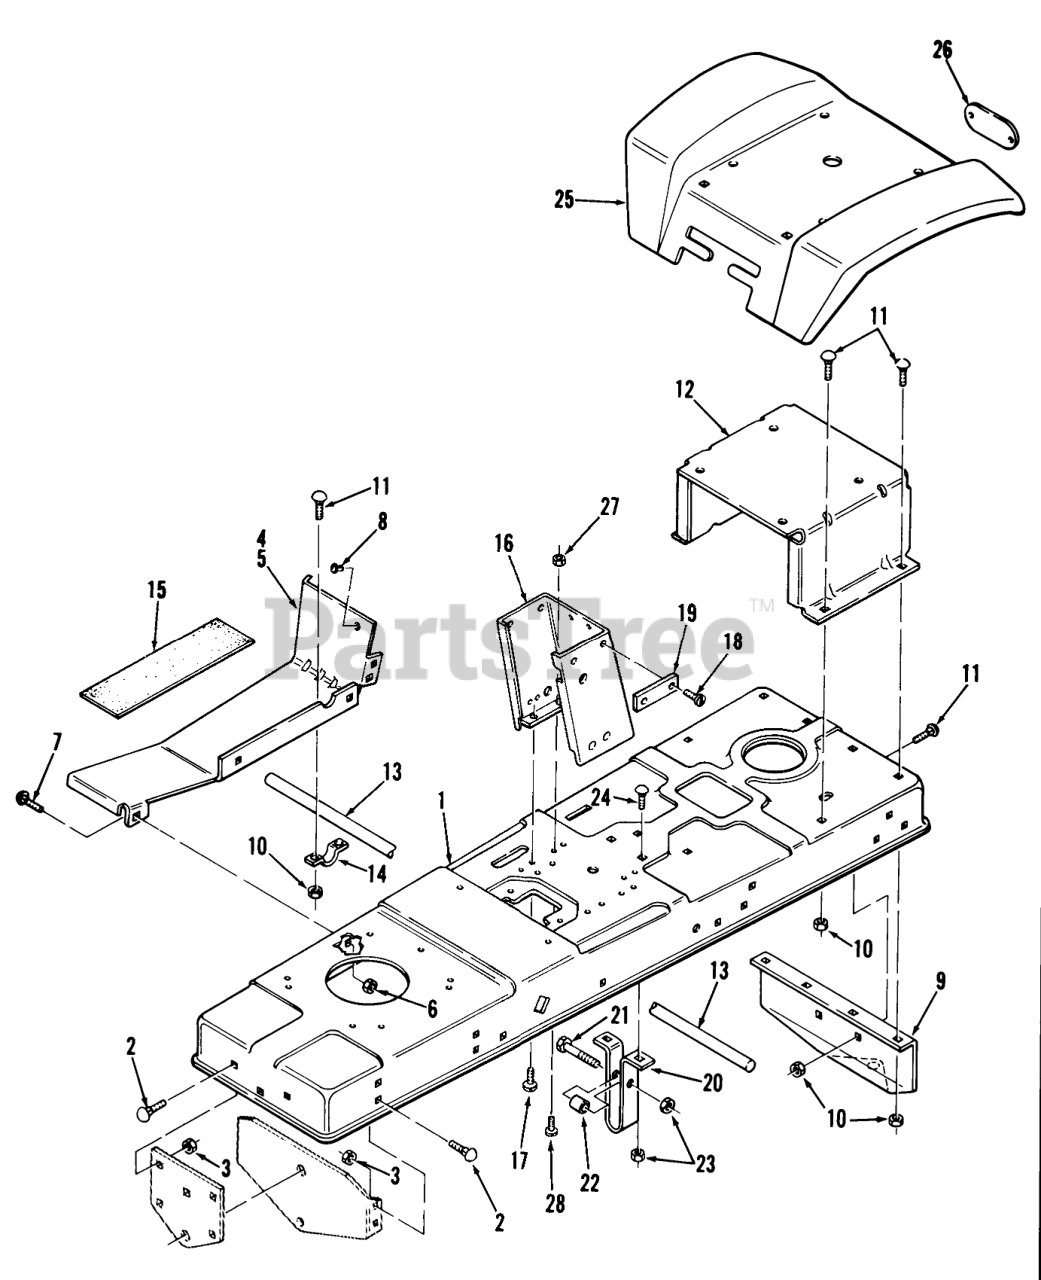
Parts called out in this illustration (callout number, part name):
1	Frame
2	CARRIAGE BOLT -4
3	Nut
4	Footrest RH
5	Footrest LH
6	Nut
7	CARRIAGE BOLT -4
8	BUMPER-RUBBER
9	HITCH-DRAWBAR
10	Nut
11	CARRIAGE BOLT -4
12	Support-Seat
13	SHAFT-REAR
14	CLAMP
15	PAD-FOOTREST
16	Hoodstand
17	SCREW
18	S.T. Screw 5/16-18 X 3/4
19	Spacer
20	Guide-Mower
21	Bolt
22	SPACER
23	Nut
24	Bolt-Carriage
25	Assy-Fender & Plate
26	REFLECTOR-STICK ON
27	Nut
28	Bolt
